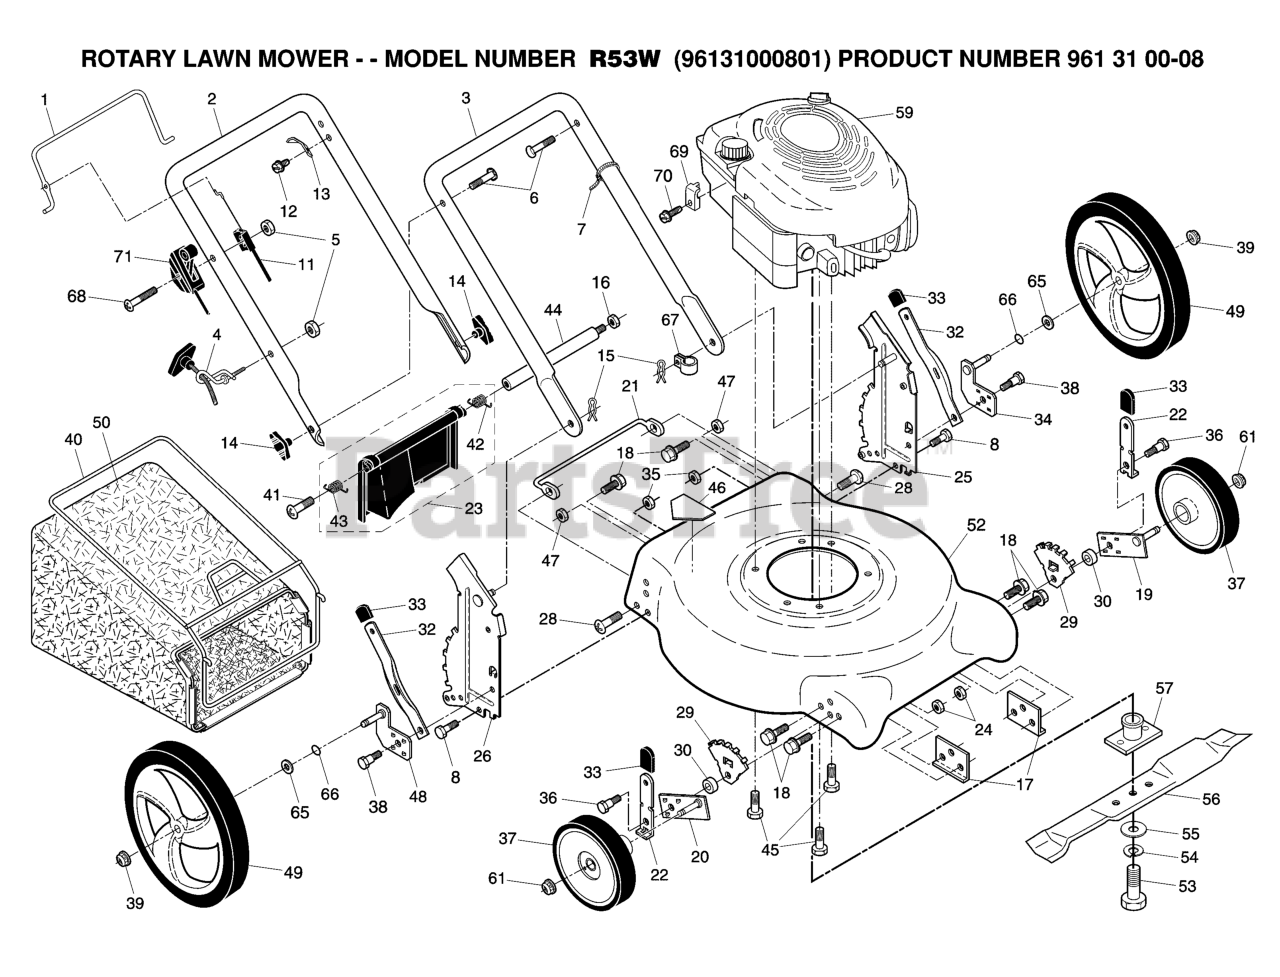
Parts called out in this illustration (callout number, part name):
2	KEY 1/4 X 2.5
7	HUB.ASM.WHEEL.REAR.23"TEX
15	WASHER
17	SPRING.BRAKE.K46
26	SPRING.RETURN.CRUISE
29	ROD.BRAKE.K66
33	E RING HYT
35	ROD .BRAKE. PARKING. GT. HUSQ.
42	PEDAL COVER T
48	BOLT.3/8-16X1.50
50	IDLER.FLAT.910.OFFSET
51	NUT LOCK FLG 3/8-16 UNC
52	IDLER.V-GROOVE.910.OFFSET
64	SHAFT.ASM.PEDAL.BRK.CNTR
70	CONSOLE.ASM.RH.GT.FC.HUSQ
73	BOLT HEX 5/16-18 GR 5
74	SCREW.HI-LO.CONSOLE
80	STRAP.TORQUE.K66
92	BOLT
99	ROD.SPRING.BYPASS.K66.GT.Z
114	NUT.71038.31-18.HEX.NYLOCK
116	NUT LOCK HEX FLANGE 5/16-18
121	BRACKET STRAP TORQUE
122	BOLT.5/16-18X2.5
125	SCREW
145	WASHER.AXLE.FLANGE.HG-3000
153	RETAINER M
159	COTTER PIN
160	RETAINER CLIP
161	SPRING, RETURN LT
163	ROD.PEDAL.CONTROL
166	NUT.PUSH.625
167	LATCH.BRAKE.SPRING
184	RB HANDLE.PARKG.BRK.HUS/PRED
186	BOLT.5/16-18X2.5
187	WASHER 12/32X2X10GA
188	RP.LINK.CLUTCH.GROUND.DRIVE
189	BELLCRANK.GROUND.DRIVE.TEX.
190	KEEPER.BELLCRANK.DRIVE
196	SCREW 3/8-16X1
197	CLUTCH.ANTIROTATION.WIREFORM.
203	WASHER
206	BRACKET.MOUNT.CRUISE.LATCH
207	LATCH.CONTROL.CRUISE
208	GEAR.SECTOR.CONTROL.CR
209	ROD.CONTROL.CRUISE.GT.
210	ROCKER.ASM.PEDAL.CONTR
211	BEARING.NYLON
213	KNOB.CONTROL.CRUSIE.HU
214	PEDAL.FORWARD.PAD.TEX
215	PEDAL.REVERSE.TEX.GT.4
220	REFLECTOR.LH.TEX GT HU
221	RETAINER.SPRING.CLIP.H
222	WASHER 21/32 X 1-1/4 X 10 GA.
225	KEEPER.BELT.TRANSAXLE.K66
306	PIN COTTER
323	SLEEVE.BELLCRANK
